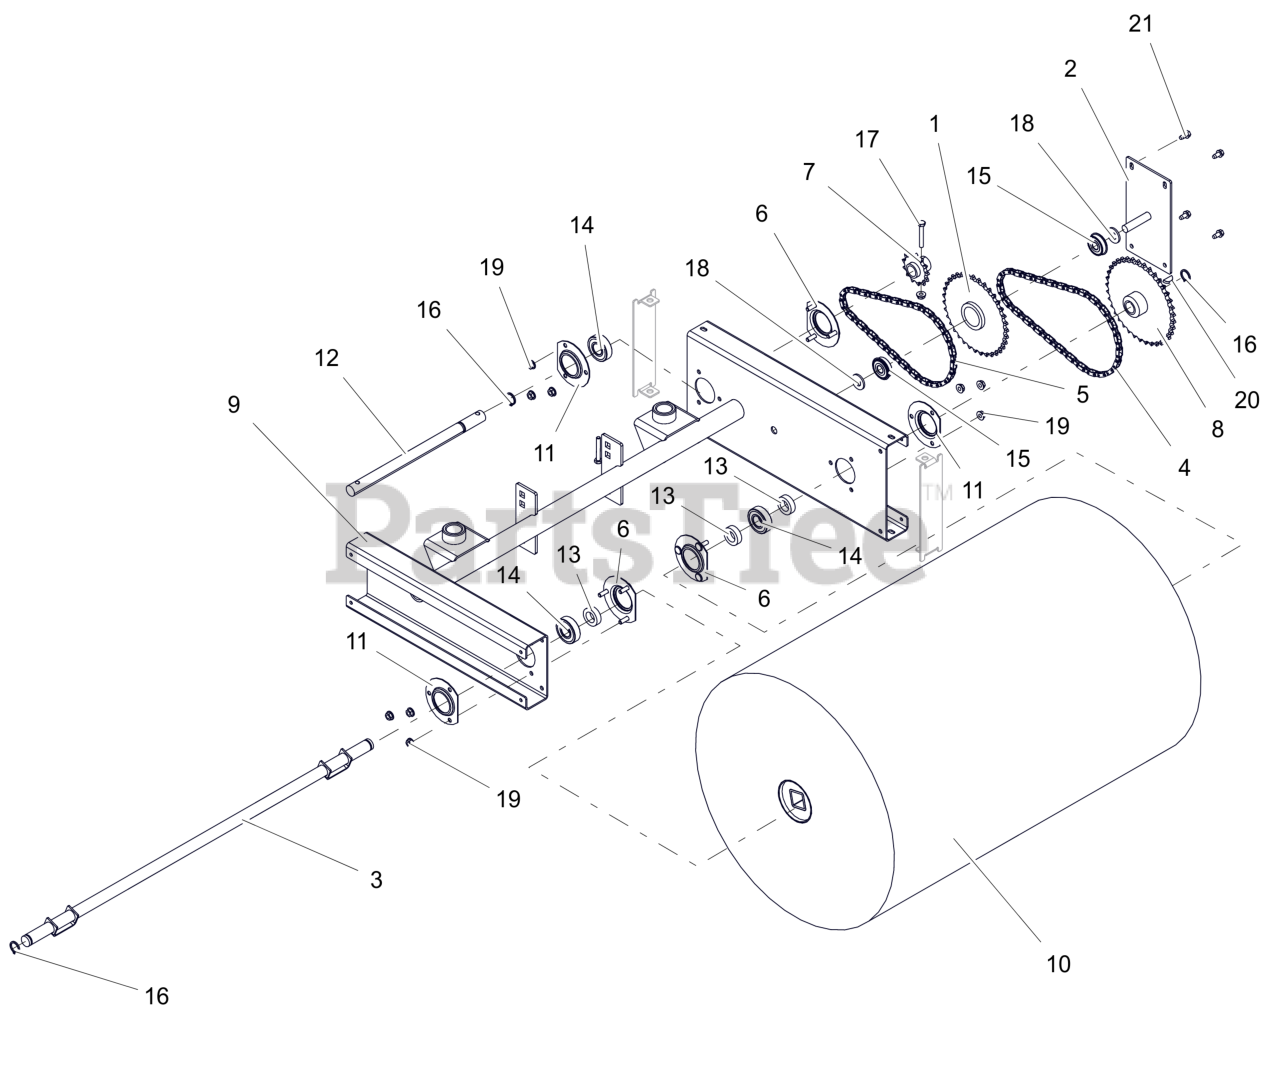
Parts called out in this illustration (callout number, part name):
1	SPROCKET, REDUCTION IDLER
2	PLATE, IDLER REDUCTION MOUNT
3	SHAFT, 28" BRUSH
4	CHAIN, #40-54 LINKS
5	CHAIN, #41-50 LINKS
6	BEARING FLANGE
7	SPROCKET, DRIVE
8	SPROCKET, DRIVEN
9	FRAME, POWER BROOM-DELUXE
10	BRUSH, 18"DIA X 28"WIDE
11	BEARING FLANGE
12	SHAFT, TRANSMISSION
13	SPACER .755X1.250X.370
14	BRG-BALL .750X1.750X.50
15	BRG-BALL .50X1.38X.438 SEALED
16	RG-RTNG-EXT .689X.078
17	@BLT-HEX .25-20X1.75 GR5 YWZC
18	WSHR-FL-STL .536X1.07X.109 YZ
19	NUT-LK-TOP-FLG .250-20 GF ZCC
20	KEY-WDRF .188X.75X.313 SAE 9
21	SCR-TAP .25-20X.50 HWH ZCC
